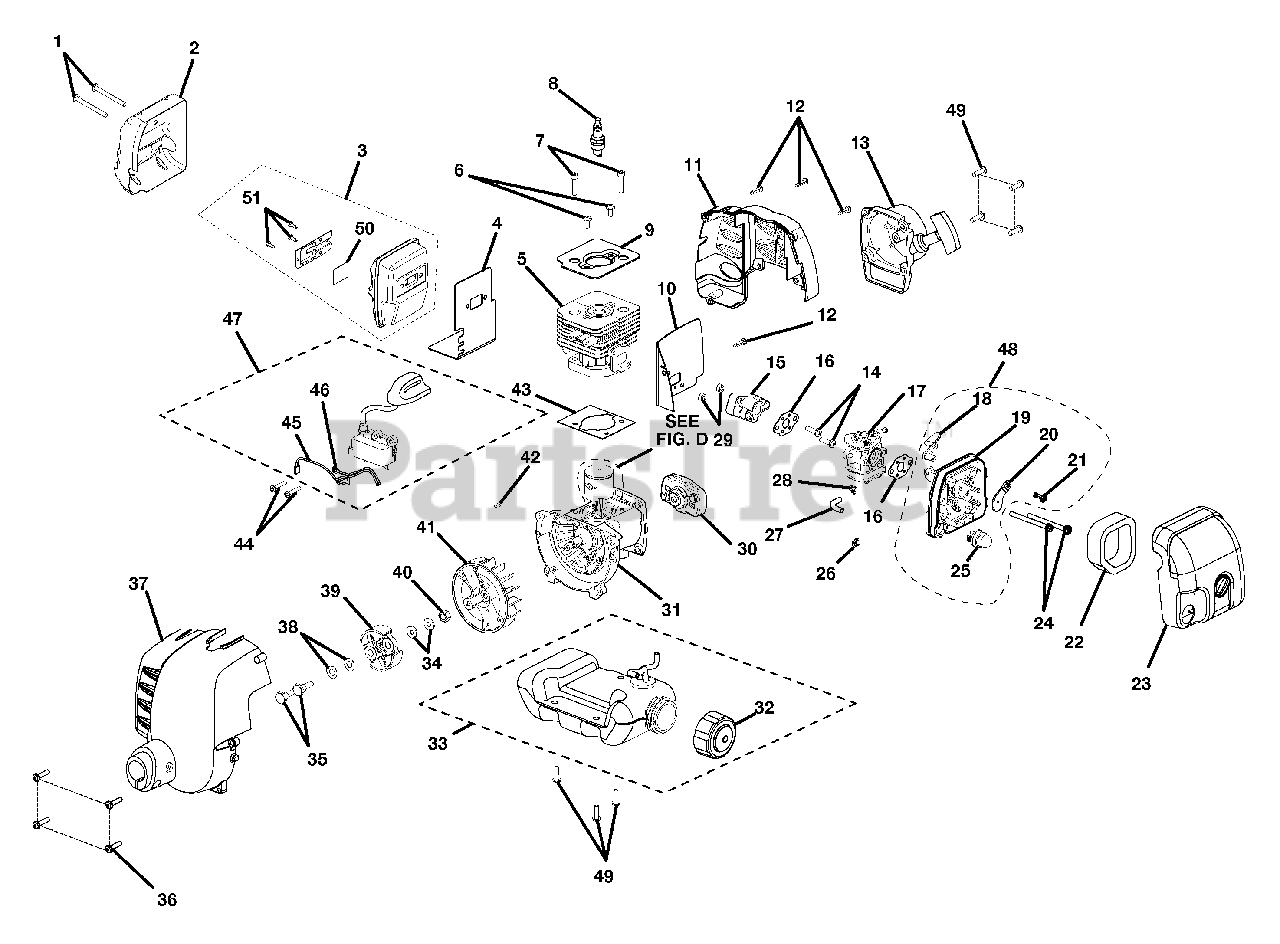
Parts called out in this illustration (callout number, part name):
1	SCREW (M5 X 50 mm TORX SLOTTED RECESSED PAN HD.)
2	HEAT SHIELD
3	MUFFLER ASSEMBLY
4	MUFFLER GASKET
5	CYLINDER
6	SCREW (M5 X 10 in. TORX RECESSED PAN HD.)
7	SCREW (M5 X 22 mm SOCKET HD.)
8	SPARK PLUG
9	CYLINDER PLATE
10	INSULATOR GASKET
11	ENGINE HOUSING, REAR
12	SCREW (M4 X 16 mm TORX RECESSED PAN HD.)
13	STARTER RECOIL ASSEMBLY
14	SCREW (M5 X 31 mm Torx SLOTTED RECESSED PAN HD.)
15	HEAT DAM INSULATOR
16	CARBURETOR GASKET
17	CARBURETOR ASSEMBLY
18	CHOKE LEVER
19	CARBURETOR PLATE
20	CHOKE PLATE
21	SCREW (M4 X 12 mm SLOTTED RECESSED PAN HD.)
22	ELEMENT
23	COVER ASSEMBLY
24	SCREW (M5 X 60 mm, SLOTTED RECESSED PAN HD. MACHINE)
25	PRIMER ASSEMBLY
26	HOSE CLIP
27	FUEL LINE
28	HOSE CLIP
29	NUT (M5 x .8 mm)
30	PULLEY ASSEMBLY
31	CRANKCASE ASSEMBLY
32	FUEL CAP ASSEMBLY
33	FUEL TANK ASSEMBLY
34	WASHER
35	CLUTCH SCREW
36	SCREW (M5 X 20 mm TORX SLOTTED RECESSED PAN HD.)
37	FRONT HOUSING ASSEMBLY
38	CURVED WASHER
39	CLUTCH ASSEMBLY
40	ROTOR NUT
41	ROTOR
42	WOODRUFF KEY (10 mm X 3 mm)
43	GASKET
44	SCREW (M4 X 22 mm TORX SLOTTED RECESSED PAN HD.)
45	LEAD ASSEMBLY, BLACK
46	LEAD ASSEMBLY, RED
47	COIL BOOT ASSEMBLY
48	FILTER HOUSING ASSEMBLY
49	SCREW (M5 X 16 MM TORX SLOTTED)
50	SCREEN
51	SCREW (RECESS PAN HD)
